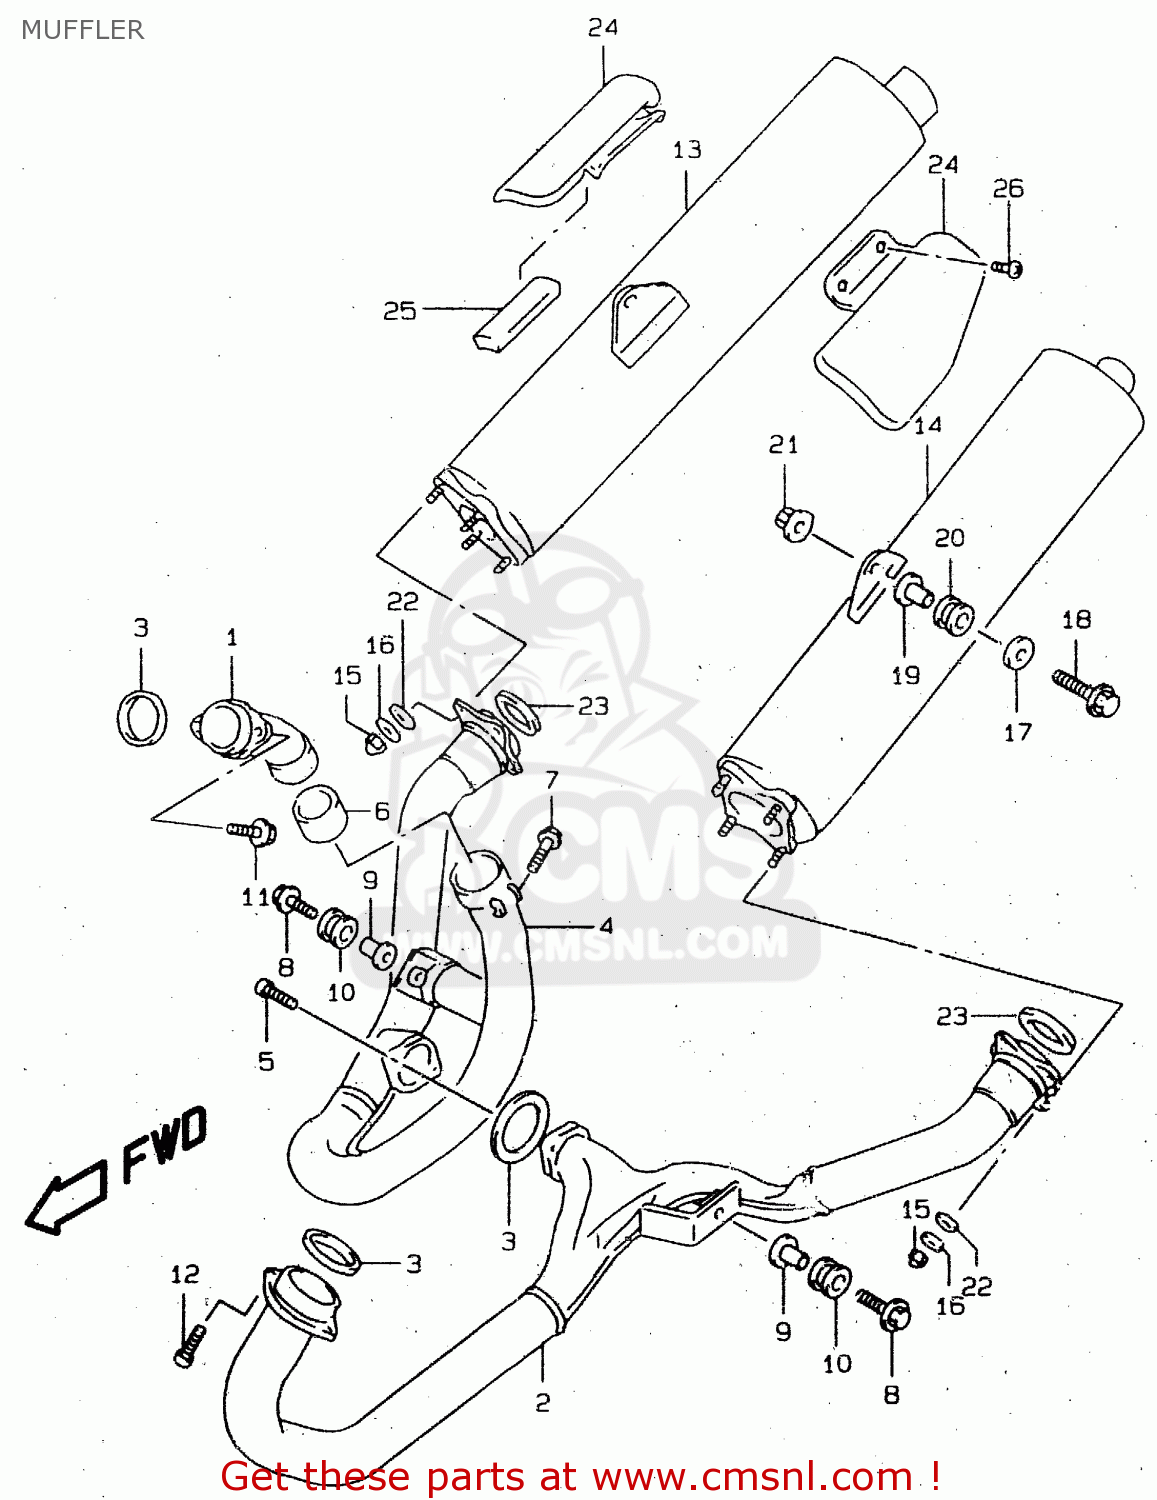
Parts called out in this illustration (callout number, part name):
1	PIPE,EXHAUST,R
2	PIPE,EXHAUST,L
3	GASKET,EXHAUST PIPE (NAS)
4	PIPE,EXHAUST JOINT,R
5	BOLT,EXH MANF
6	CONNECTOR,EXHAUST,R
7	BOLT
8	BOLT 8X45
9	SPACER(8.6X12X24.2)
10	CUSHION
11	BOLT
12	BOLT
13	BODY,MUFFLER,R
14	BODY,MUFFLER,L
15	NUT
16	WASHER(8.5X18X1.6)
17	WASHER (8.5X33X1.6)
18	BOLT
19	SPACER(8.6X12X27.1)
20	CUSHION
21	NUT
22	O RING(D:1.9,ID:7.8)
23	GASKET,MUFFLER JOINT (NAS)
24	PROTECTOR,MUFFLER,R
25	CUSHION,MUFFLER COVERER
26	SCREW(6X12)
